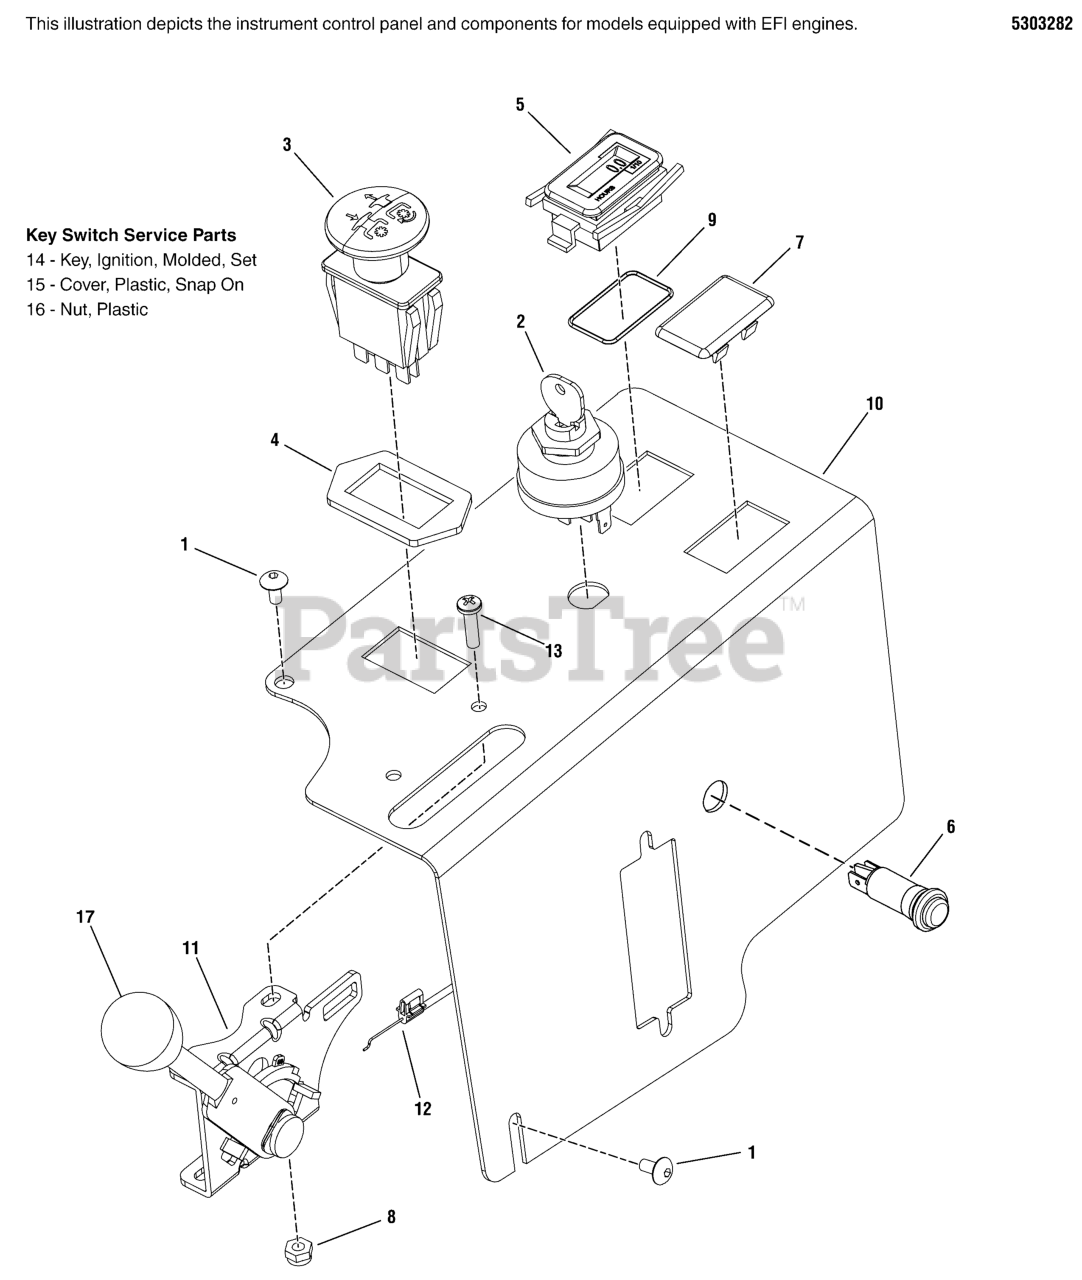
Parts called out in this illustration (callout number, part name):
1	SCREW, ALLEN HEAD 1/4-20X.500 ZINC PHOS
2	SWITCH, IGNITION, 6 POST
3	SWITCH, BLADE ENGAGEMENT
4	RING, SWITCH RETAINER
5	* HOUR METER, ASSEMBLY
6	LIGHT, INDICATOR, PANEL, LED, RED
7	PLUG, .820X1.44 HOLE, BLACK PLASTIC
8	NUT, #10-24 HEX NYLON LOCK
9	O-RING, 7/8 ID X 1/16 W
10	PLATE, CONTROL PANEL, KOHLER, S200XT - BLK
10	PLATE, CONTROL PANEL, 200XT, EFI
11	LEVER, THROTTLE CONTROL, HEAVY-DUTY
12	CABLE, THROTTLE, 42"
13	SCREW, #10-24 X 3/4 ROUND PHILLIPS
14	KEY, IGNITION MOLDED SET
15	COVER, PLASTIC, SNAP ON
16	PLASTIC NUT
